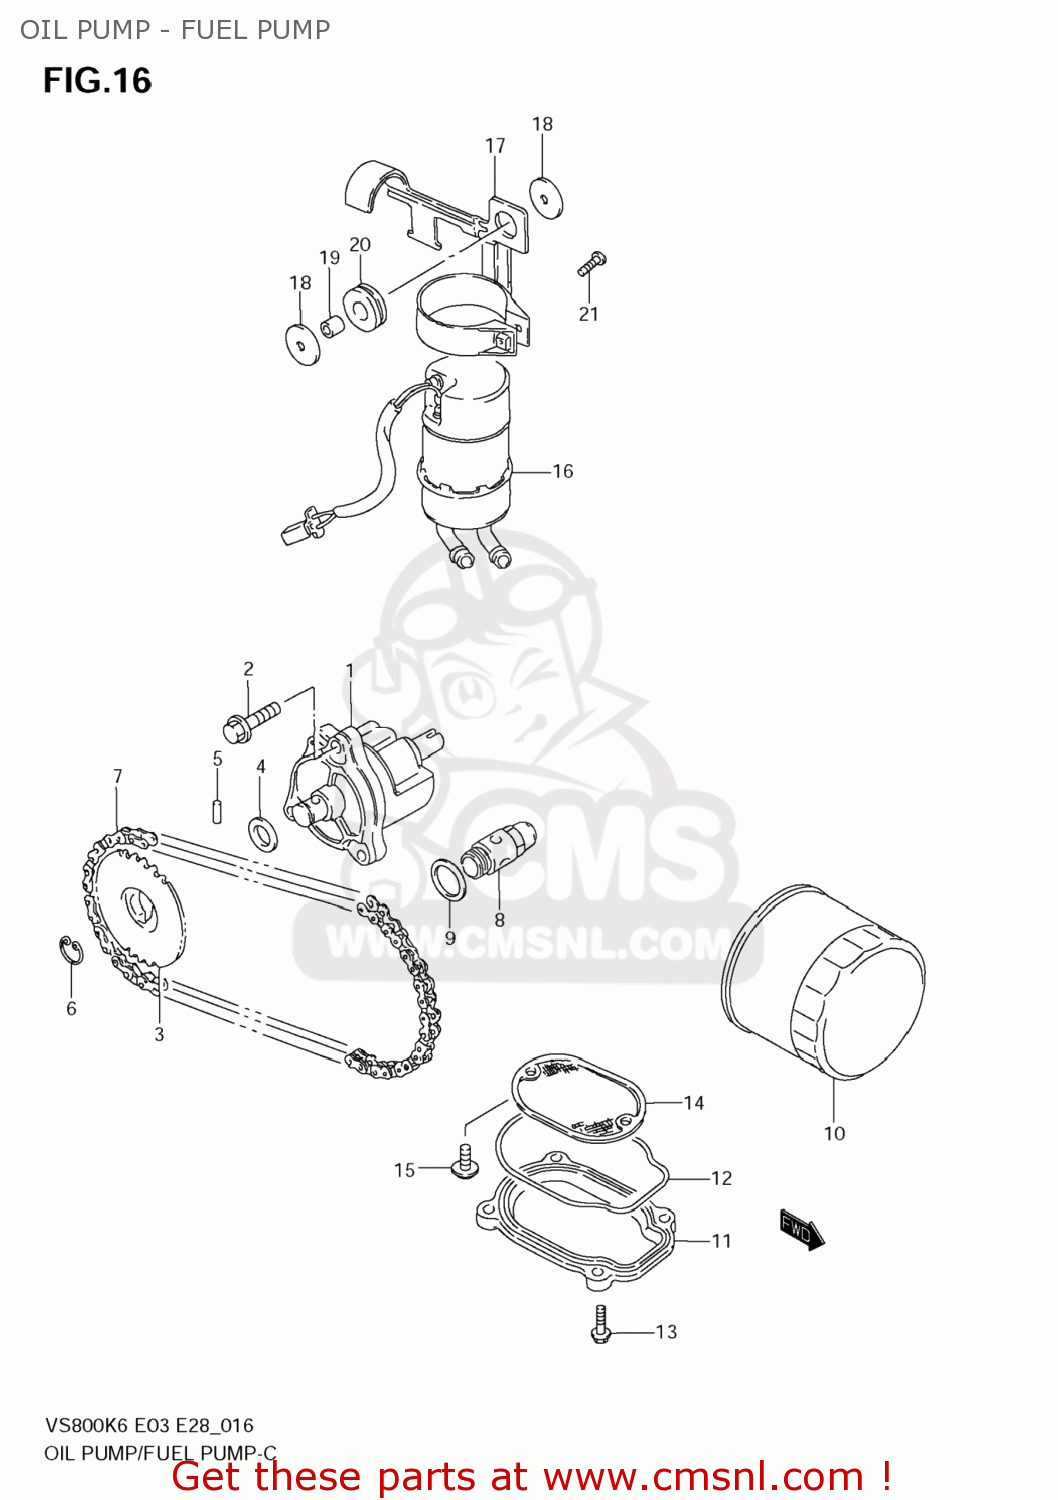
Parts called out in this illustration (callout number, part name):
1	PUMP ASSY,ENGINE OIL
2	BOLT
3	SPROCKET,OIL PUMP DRIVEN
4	SHIM(12X20X0.5)
5	PIN(5X18)
6	CIRCLIP,12 MM
7	CHAIN,OIL PUMP DRIVE
8	VALVE ASSY,OIL RELIEF
9	GASKET(16X22X2) (NAS)
10	FILTER ASSY,EN
11	CAP,OIL STRAINER
12	O RING,OIL STRAINER CAP
13	BOLT
14	STRAINER,ENGINE OIL
15	SCREW
16	PUMP ASSY,FUEL
17	BRACKET,FUEL PUMP
18	WASHER
19	SPACER(6.5X10.5X6.5)
20	CUSHION
21	SCREW
